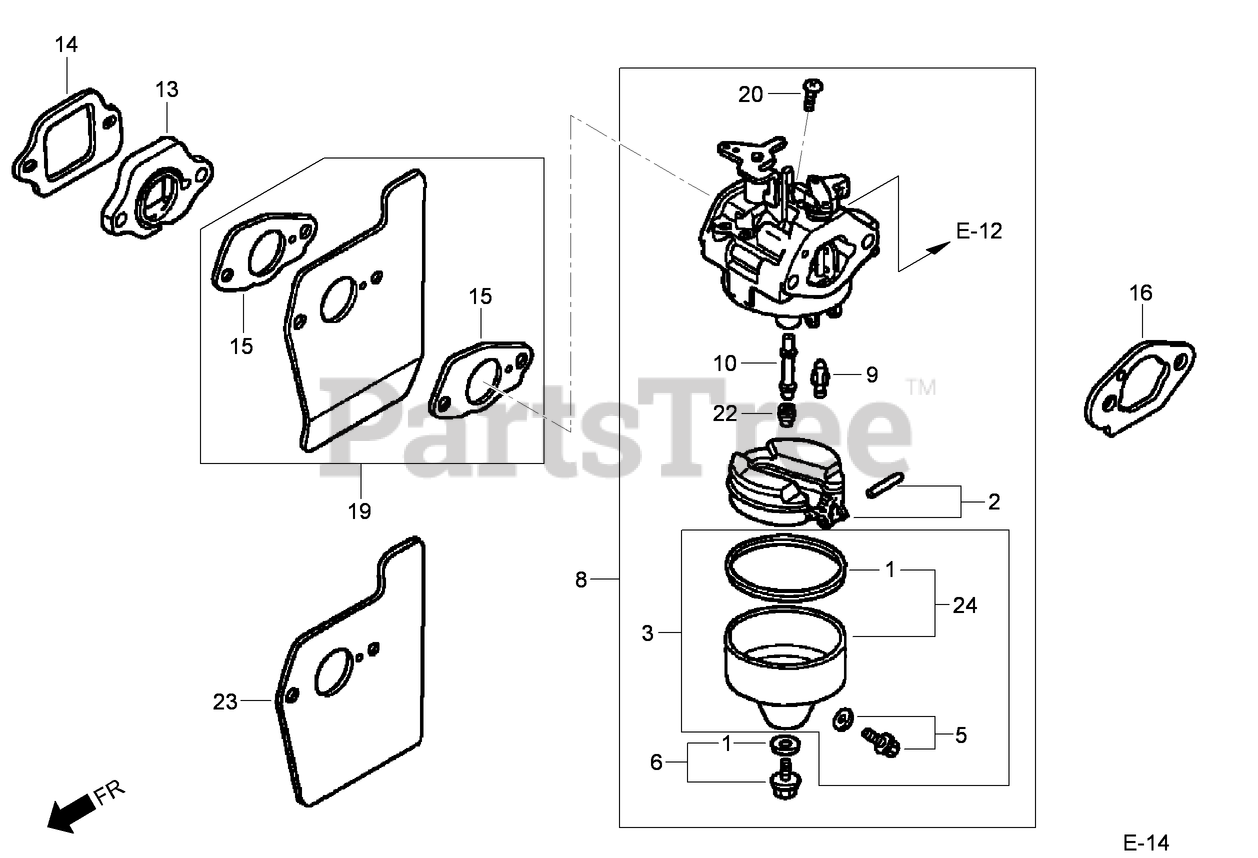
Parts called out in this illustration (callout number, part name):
1	GASKET SET
2	FLOAT SET
3	FLOAT CHAMBER SET (engine serial numbers up to B B62Z A)
5	DRAIN SCREW SET
6	SCREW SET
8	CARBURETOR ASSY (B B62Z A) (engine serial numbers up to 7161134)
8	CARBURETOR ASSY (B B62Z B) (engine serial numbers starting at 7161135)
9	VALVE-FLOAT
10	NOZZLE-MAIN
13	INSULATOR-CARBURETOR
14	GASKET-INSULATOR
15	GASKET-CARBURETOR (engine serial numbers up to 6349022)
16	GASKET-CARBURETOR
19	GUIDE-AIR (engine serial numbers up to 6349022)
20	SCREW-PAN (5X6)
22	JET-MAIN (No.60) (Optional Equipment)
22	JET-MAIN (No.62) (Optional Equipment)
22	JET-MAIN (No.65)
23	GUIDE-AIR (engine serial numbers starting at 6349023)
24	FLOAT CHAMBER SET (engine serial numbers starting at B B62Z B)
